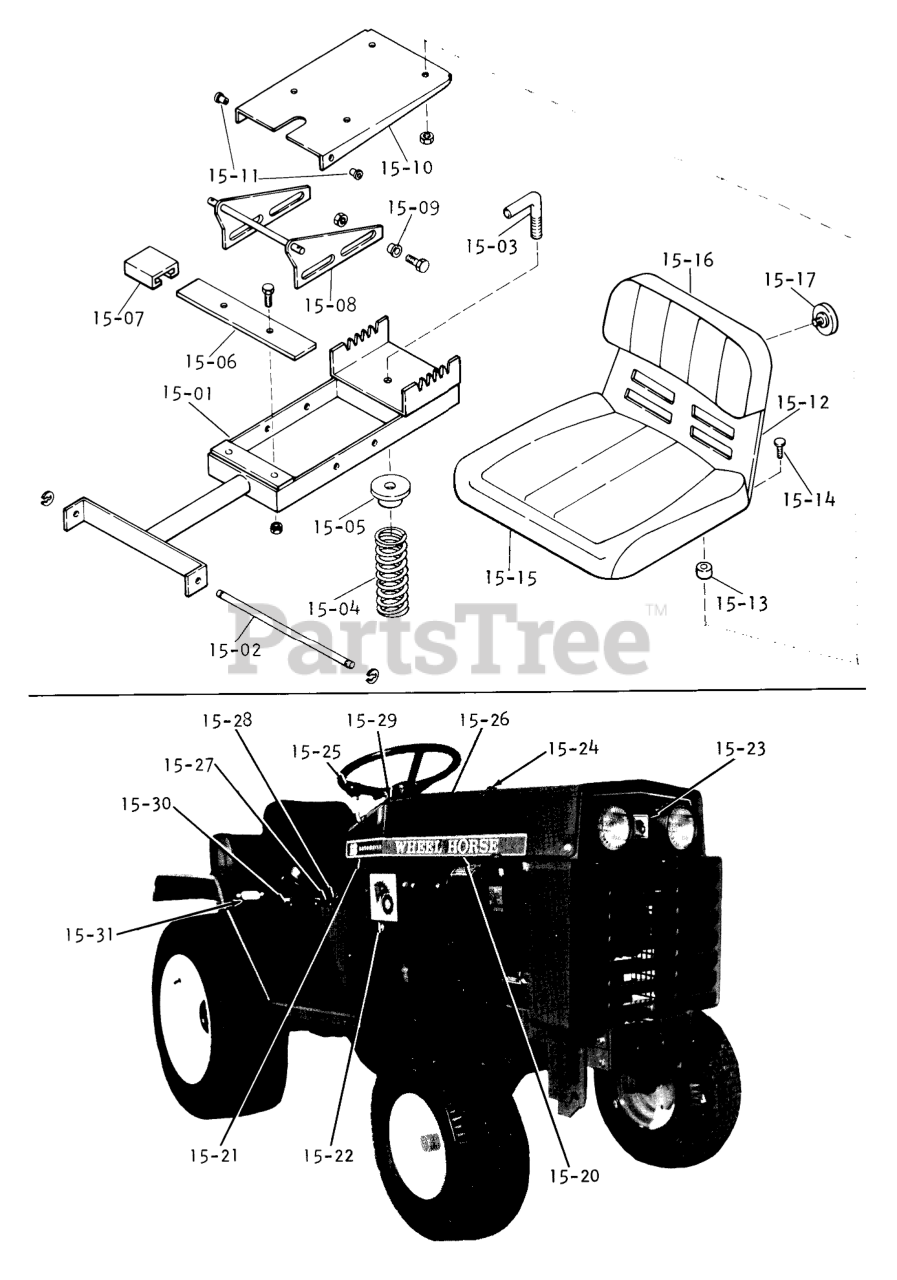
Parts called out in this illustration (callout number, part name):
15-01	Seat Pivot Assembly
15-02	Rod-Pivot
15-03	Rod-Adjusting
15-04	Spring
15-05	Block-Spring
15-06	Bar-Seat Stop
15-07	Bumper-Rubber
15-08	Seat Adjustment Assembly
15-09	SPACER
15-10	Plate-Seat Adjustment
15-11	NYLINER BUSHING
15-12	Seat Base Assy.
15-13	Spacer
15-14	Bolt-Car. 5/16-18 x 1
15-15	Cushion Seat
15-16	Back Cushion
15-17	Wing Head Stud
15-20	Decal
15-21	Decal-18 Automatic
15-22	Gear Shift Quadrant
15-23	Decal
15-24	Decal-Clutch Knob
15-25	Decal-Hydro Control Knob
15-26	Decal
15-27	Decal-Parking Brake-on access cover plate
15-28	Decal
15-29	Decal
15-30	Decal
15-31	Reflector
